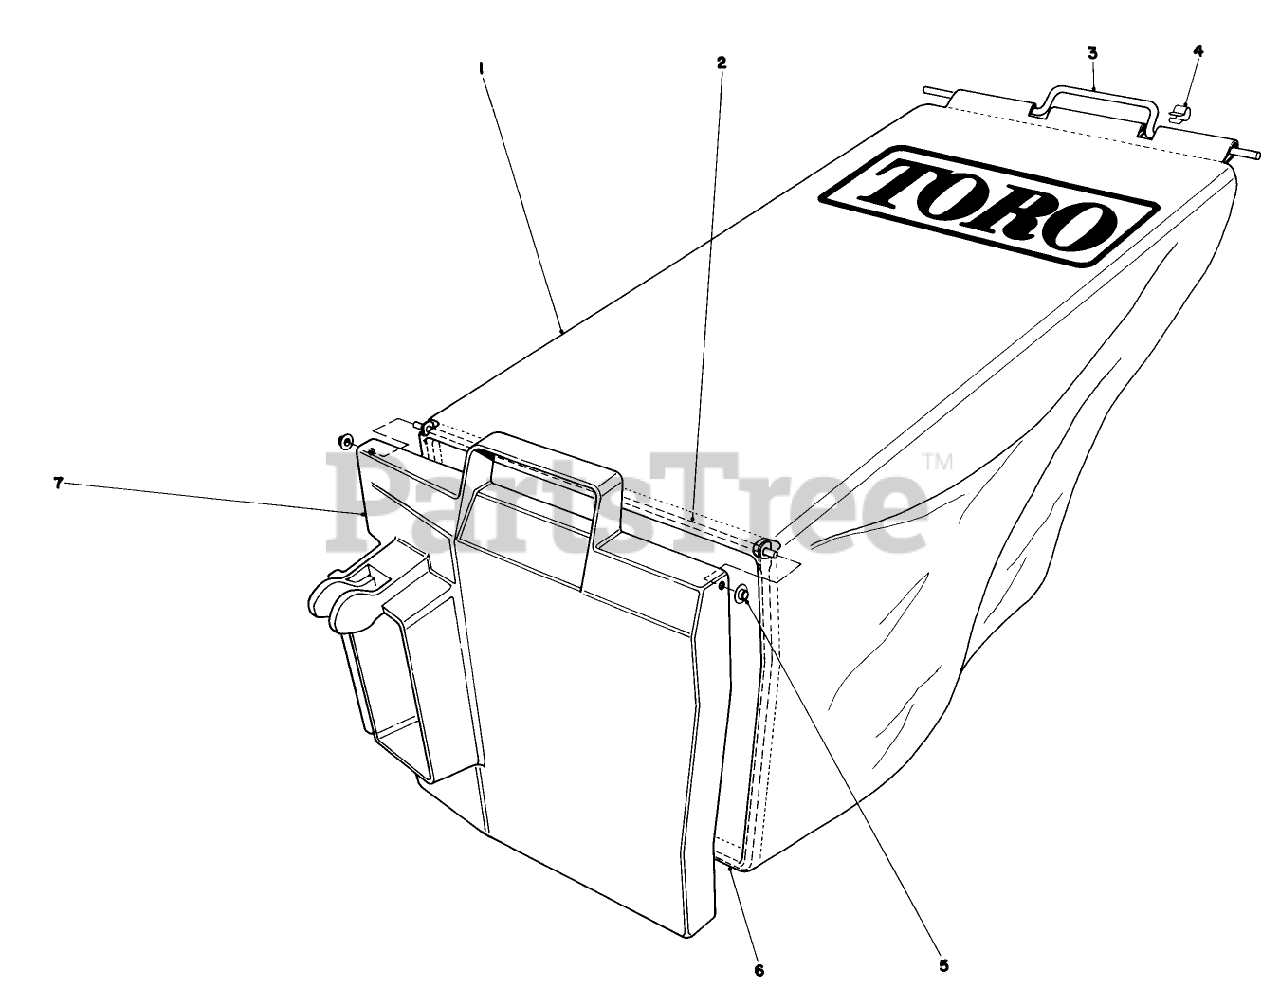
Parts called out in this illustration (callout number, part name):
1	18 BAGGER BAG 33-4552
2	HINGE
3	Handle Bag
5	NUT-PUSH
6	Frame Bag
7	Door-Bag
